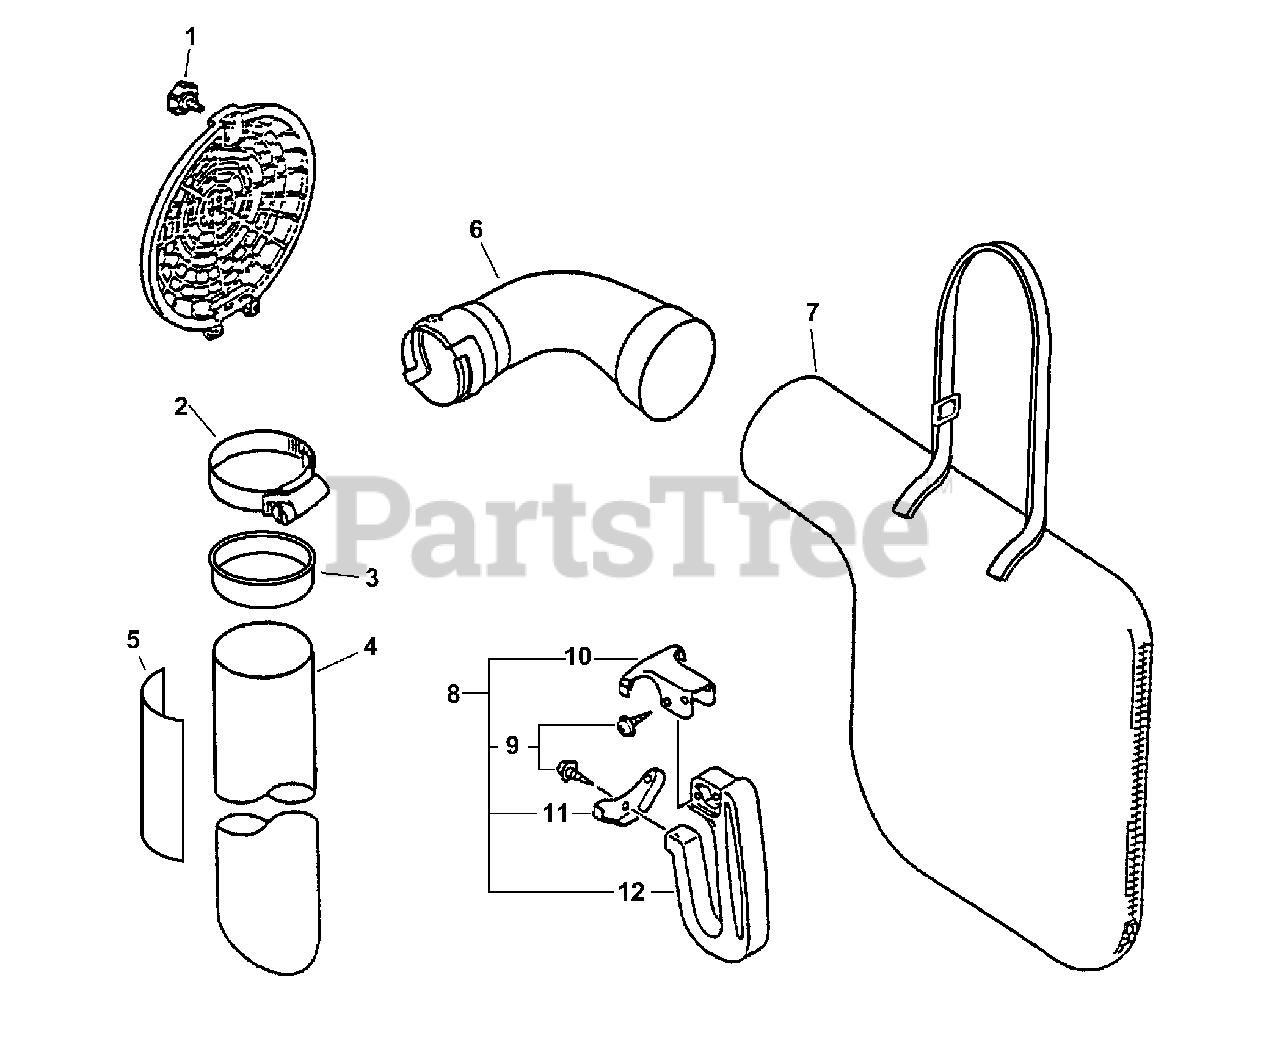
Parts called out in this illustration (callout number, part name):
1	THUMBSCREW
4	TUBE, VACUUM
5	LABEL, ECHO BLOWER TUBE
7	BAG, DUST
8	HANDLE ASSY, SIDE
9	SCREW 5×14
10	BRACKET, UPPER HANDLE
11	BRACKET, LOWER HANDLE
